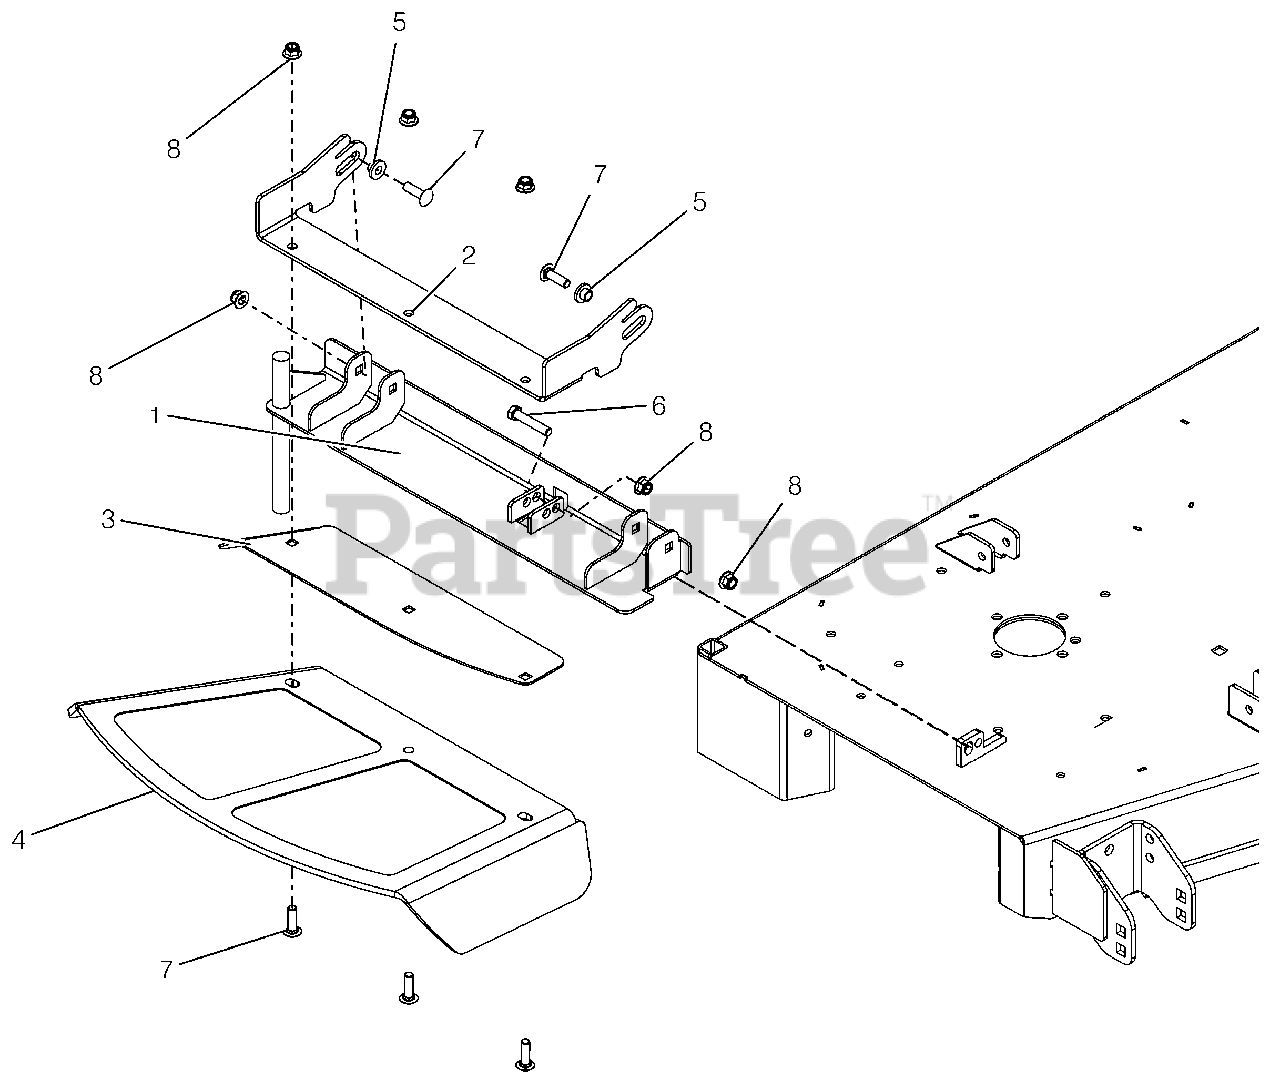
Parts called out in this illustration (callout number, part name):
1	48-60 DISCH CHT MTG WMT W/SAFE
2	48-60" CHUTE MTG BRKT - RED
3	48-60 DISCH CHUTE CLMP PLT-RED
4	CHUTE,48-60" FRMD RUBBER DISCH
5	BSHG-FLG .385X.500X.875X.406
6	@BLT-HEX .38-16X2.00 GR5 YWZC
7	@BLT-RHDSSQNK .38-16X1.25 G5YZ
8	@NUT-LK-NYL-FLG .38-16 YWZC
